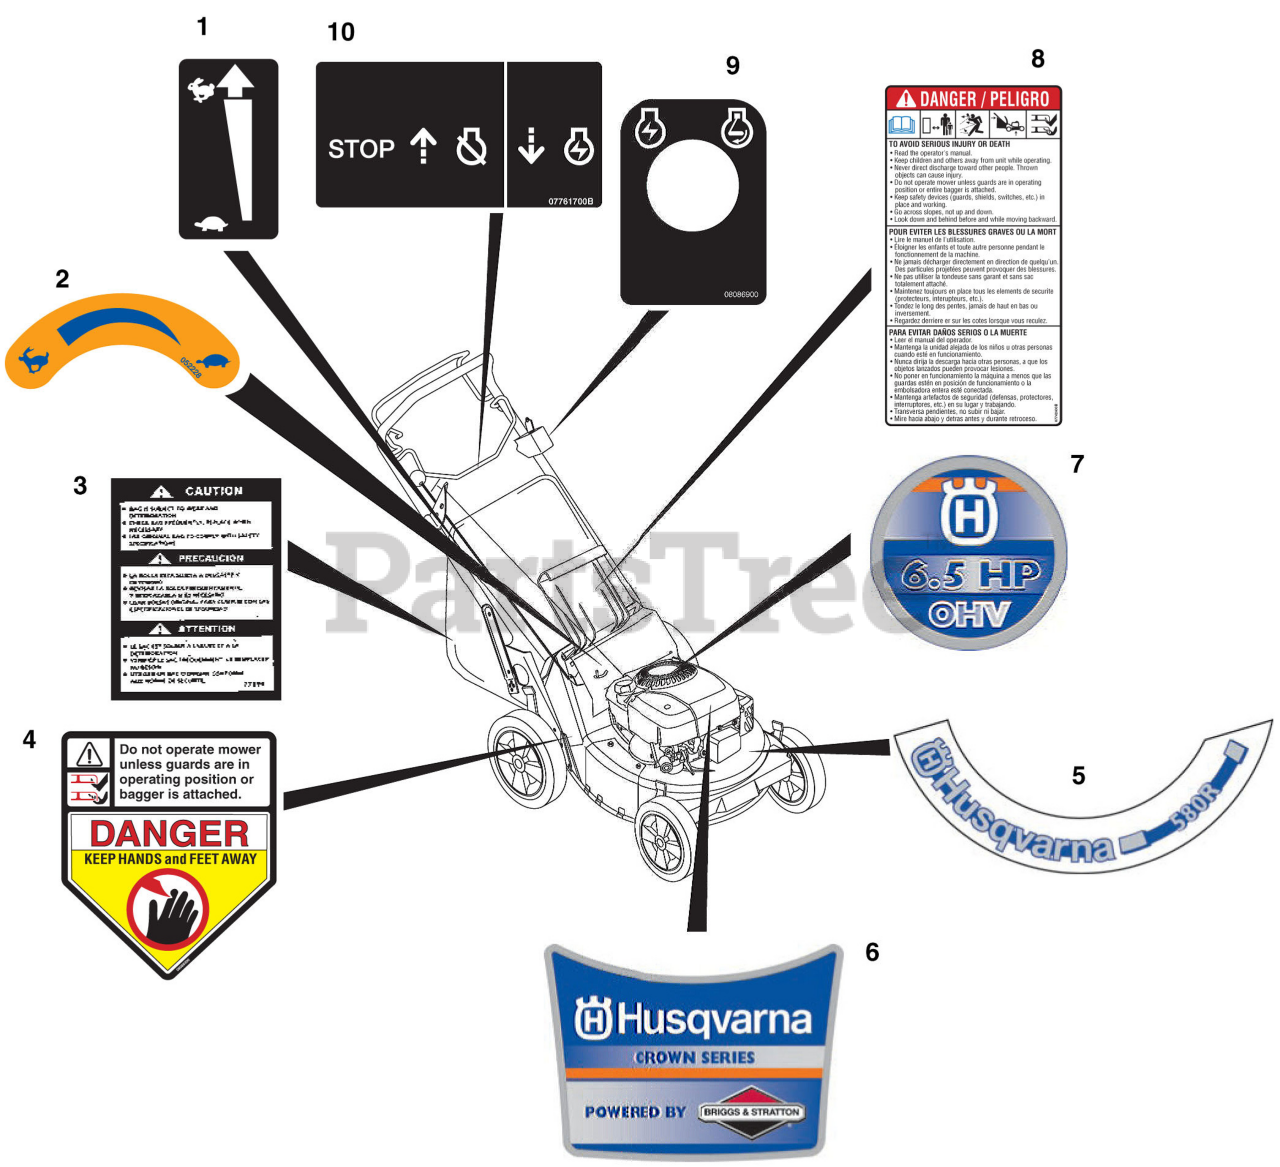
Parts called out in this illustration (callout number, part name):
1	Decal, Speed Control
2	Decal, Swoosh Husqvarna
3	Label, Bagger 21''
4	Decal, Danger
5	Decal, 580 R
6	Decal, Husqvarna & Robin (600 C)
7	Decal, Robin 6HP OHV-Commercial (600 C)
8	Decal, Bilingual Danger
9	Decal, Key Switch (580 RSE)
10	Decal, Engine Control
